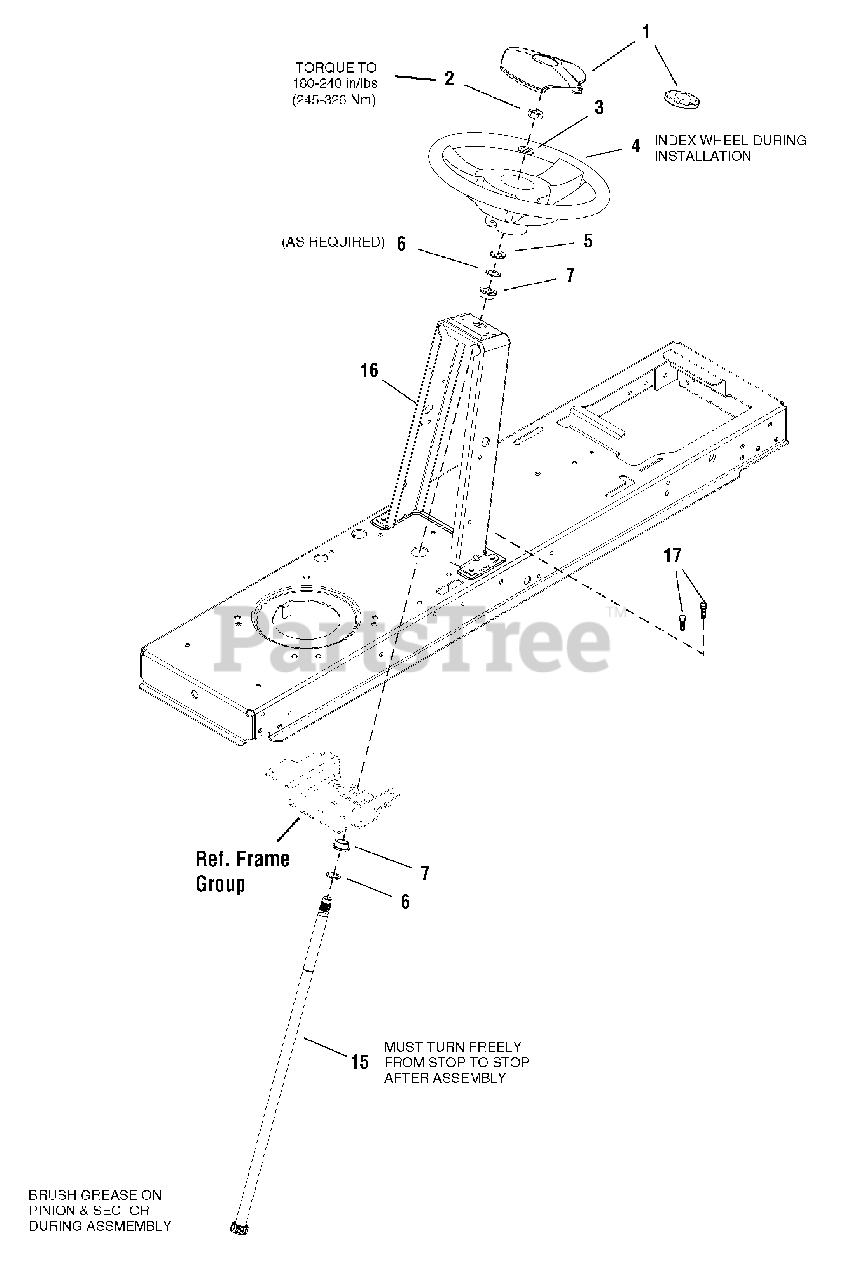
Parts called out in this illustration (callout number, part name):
1	CAP, Steering Wheel, Simplicity
1	CAP, Steering Wheel, Plain
2	NUT, Hex Lock, ESNA Light, 5/8-18, Thin
3	WASHER, 5/8 x 1-1/8
4	STEERING WHEEL, w/Aluminum Insert
5	RING, Klipring Extension
6	WASHER, 3/4 x 1
7	BUSHING, Steering
15	SHAFT, Steering Gear & Spline Yellow
16	TOWER
17	SCREW, Hex Washer Head, Taptite
